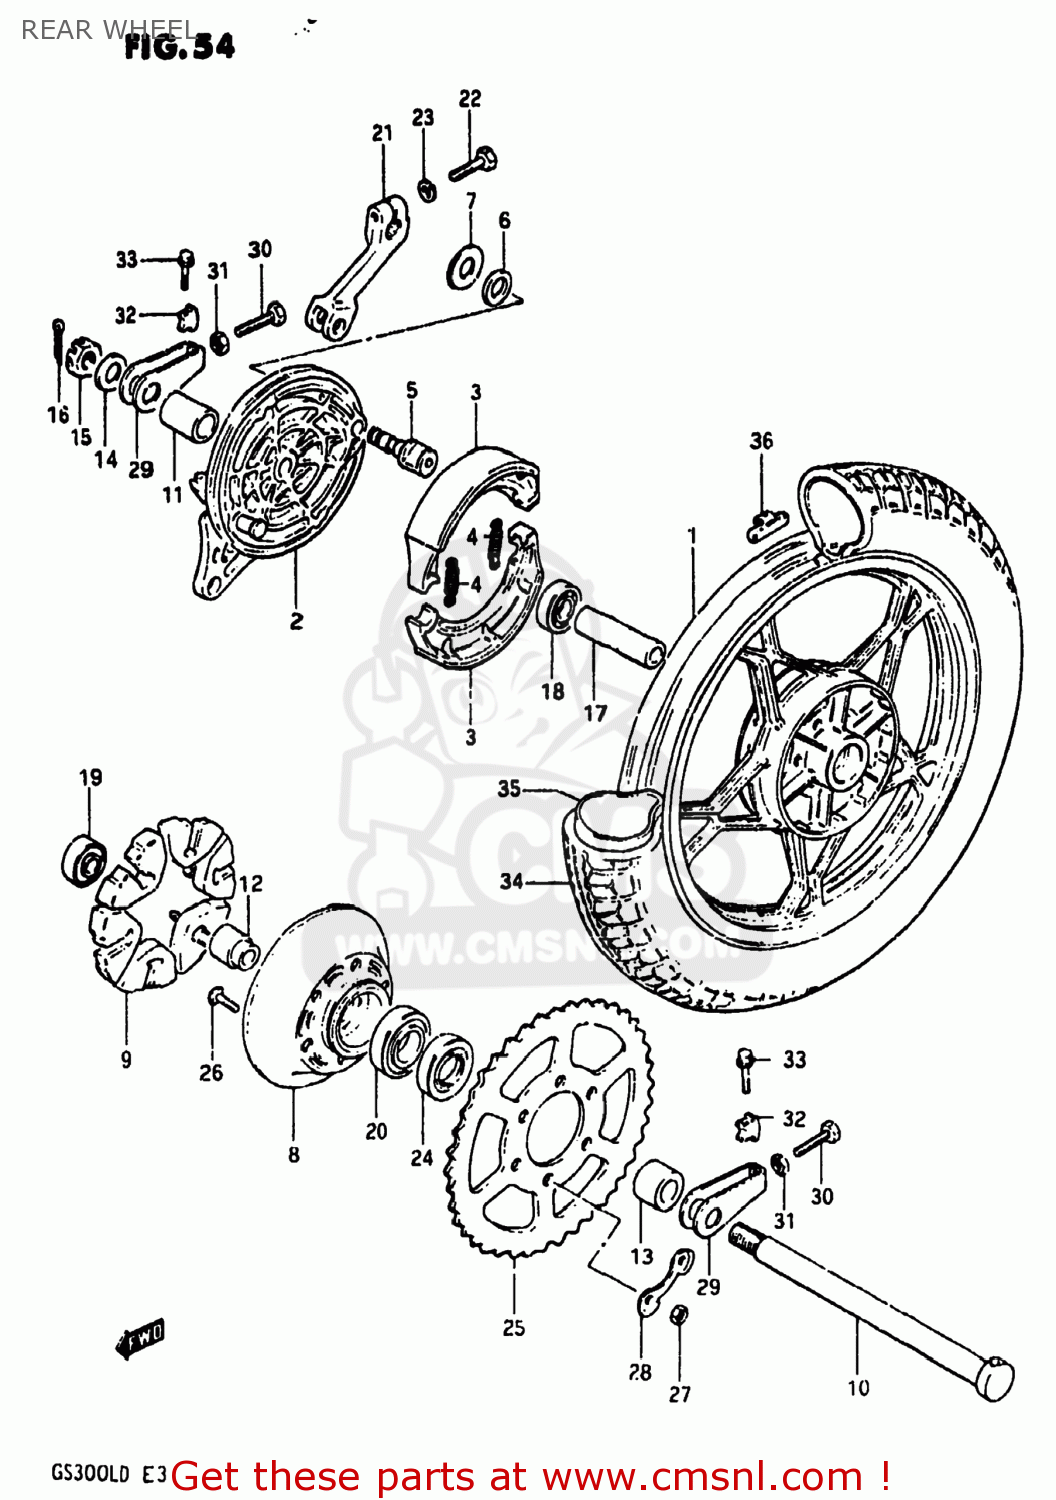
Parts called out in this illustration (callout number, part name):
1	CASTING WHEEL,REAR 2.15
2	PANEL,REAR HUB
3	SHOE,BRAKE
4	SPRING,BRAKE SHOE
5	CAM,FRONT BRAKE
6	O-RING,BOSS
7	WASHER (15X24X1.6)
8	DRUM,REAR SPROCKET MOUNT
9	ABSORBER,RR HUB SHOCK
10	AXLE,REAR
11	SPACER(17.5X28X44.8)
12	SPACER,REAR HUB BEARING
13	SPACER(17X30.5X22.3)
14	WASHER (17X30X3.2)
15	NUT
16	PIN,COTTER
17	SPACER (17.6X24X57)
18	BEARING
19	BEARING
20	BEARING
21	LEVER,RR BRAKE CAM
22	BOLT
23	LOCK WASHER
24	SEAL,OIL(30.5X52X8)
25	SPROCKET,REAR (NT:42)
26	BOLT
27	NUT
28	WASHER
29	ADJUSTER,CHAIN
30	BOLT 8X50
31	NUT
32	SUPPORTER,CHAIN ADJUST
33	BOLT
34	TIRE
35	TUBE ASSY,WHEEL,INNER 4.60-16
36	BALANCER,WHEEL
